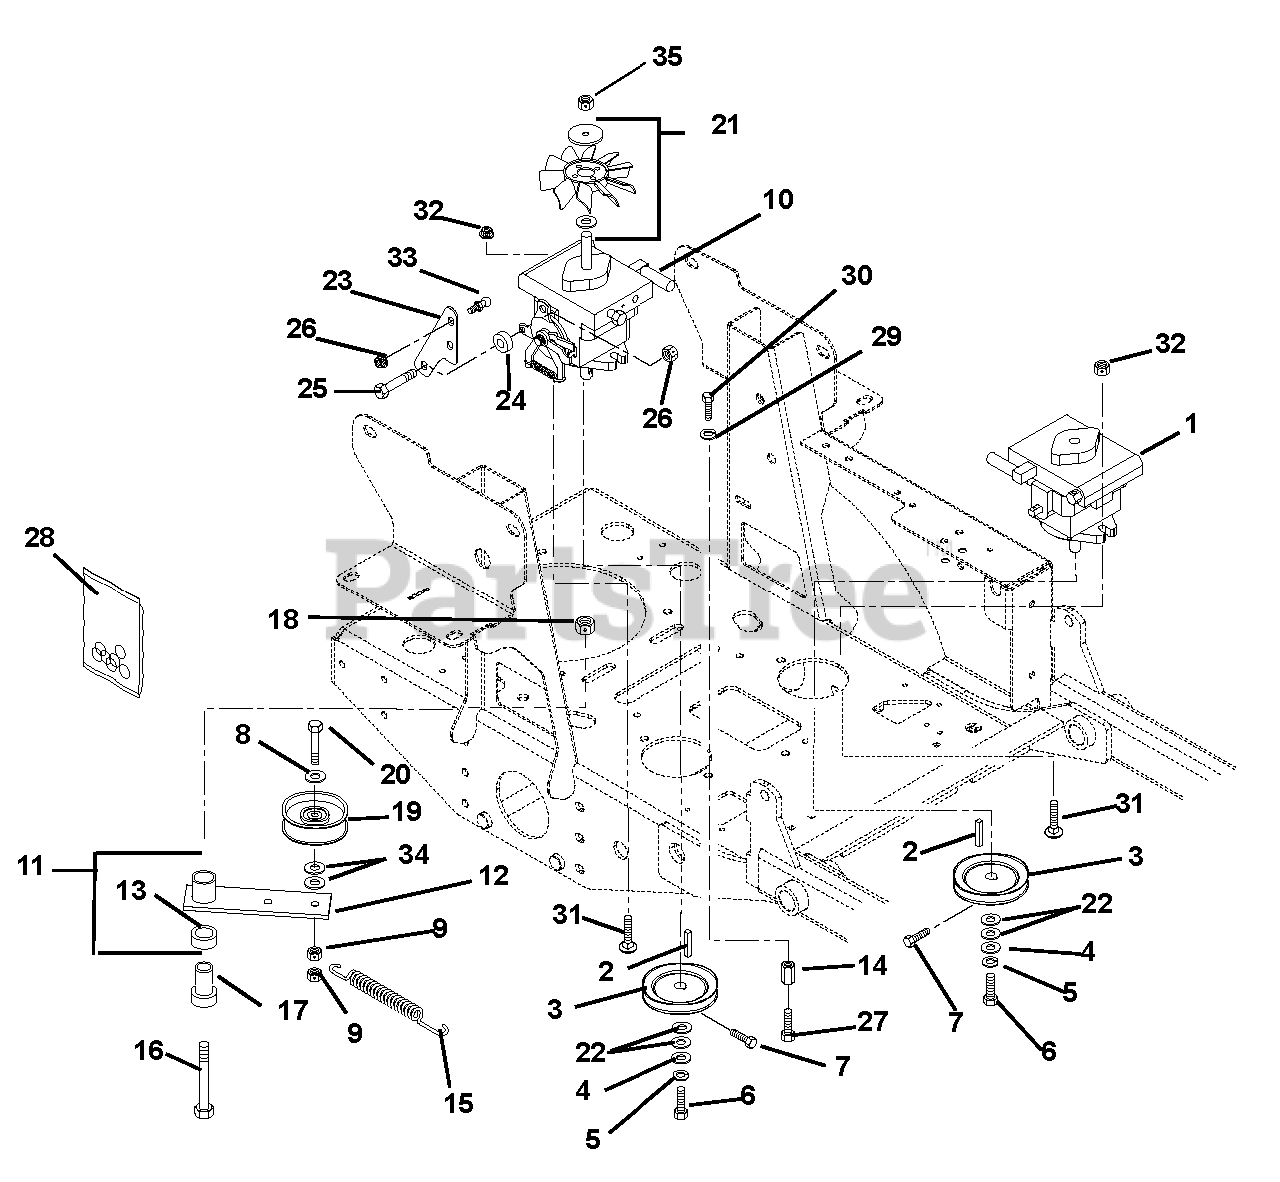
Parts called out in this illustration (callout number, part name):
1	Pump, Hydraulic BDP-10A Left Hand
2	Key, Straight 5mm x 25mm x 5mm
3	Sheave 4.0 x .199
4	Washer, Flat Steel .281 x 1.00 x .063
5	Washer, Locking .25 x .062
6	Bolt, Hex M6 x 1.00 x 12 Epoxy 30
7	Bolt, Hex .25-20 x .50 Grade 5
8	Washer, Flat Steel .406 x .812 x .065
9	Nut, Nyloc Flange .38-16
10	Pump, Hydraulic BDP-10A Right Hand
11	Assembly, Idler Arm Guard Drive (Includes 12 & 13)
12	Weldment, Idler Arm Ground Drive
13	Bearing, 1.00 x 1.12 x .75
14	Nut, Coupling .375-16 x 1.75
15	Spring, Tension .120 x .845 x 6.50
16	Bolt, Hex .50-13 x 3.75 Grade 5
17	Bearing, Pedestal
18	Nut, Nyloc Flange .50-13
19	Idler, Flat 4.00 x .38 I.D.
20	Bolt, Hex .38-16 x 2.50 Grade 5
21	Fan, Cooling
22	Washer, Flat Steel .656 x 1.31 x .095
23	Bracket, Return to Neutral/Damper
24	Spacer .344 x 1.00 x .375
25	Bolt, Hex .31-18 x 1.25 Grade 5
26	Nut, Nyloc Flange .312-18
27	Bolt, Hex .38-16 x 1.50 Grade 5
28	Kit, Pump Seal (BDP-10A) (One kit required for each pump)
29	Washer, Locking .38 x .094
30	Bolt, Hex .38-16 x .75 Grade 5
31	Bolt-Round Head Square Neck .44-14 x 1.50 Grade 5
32	Nut, Nyloc Flange .44-14
33	Stud, Ball
34	Washer, Flat Steel .406 x 1.00 x .188
35	Nut, Center-Lock .31-24
